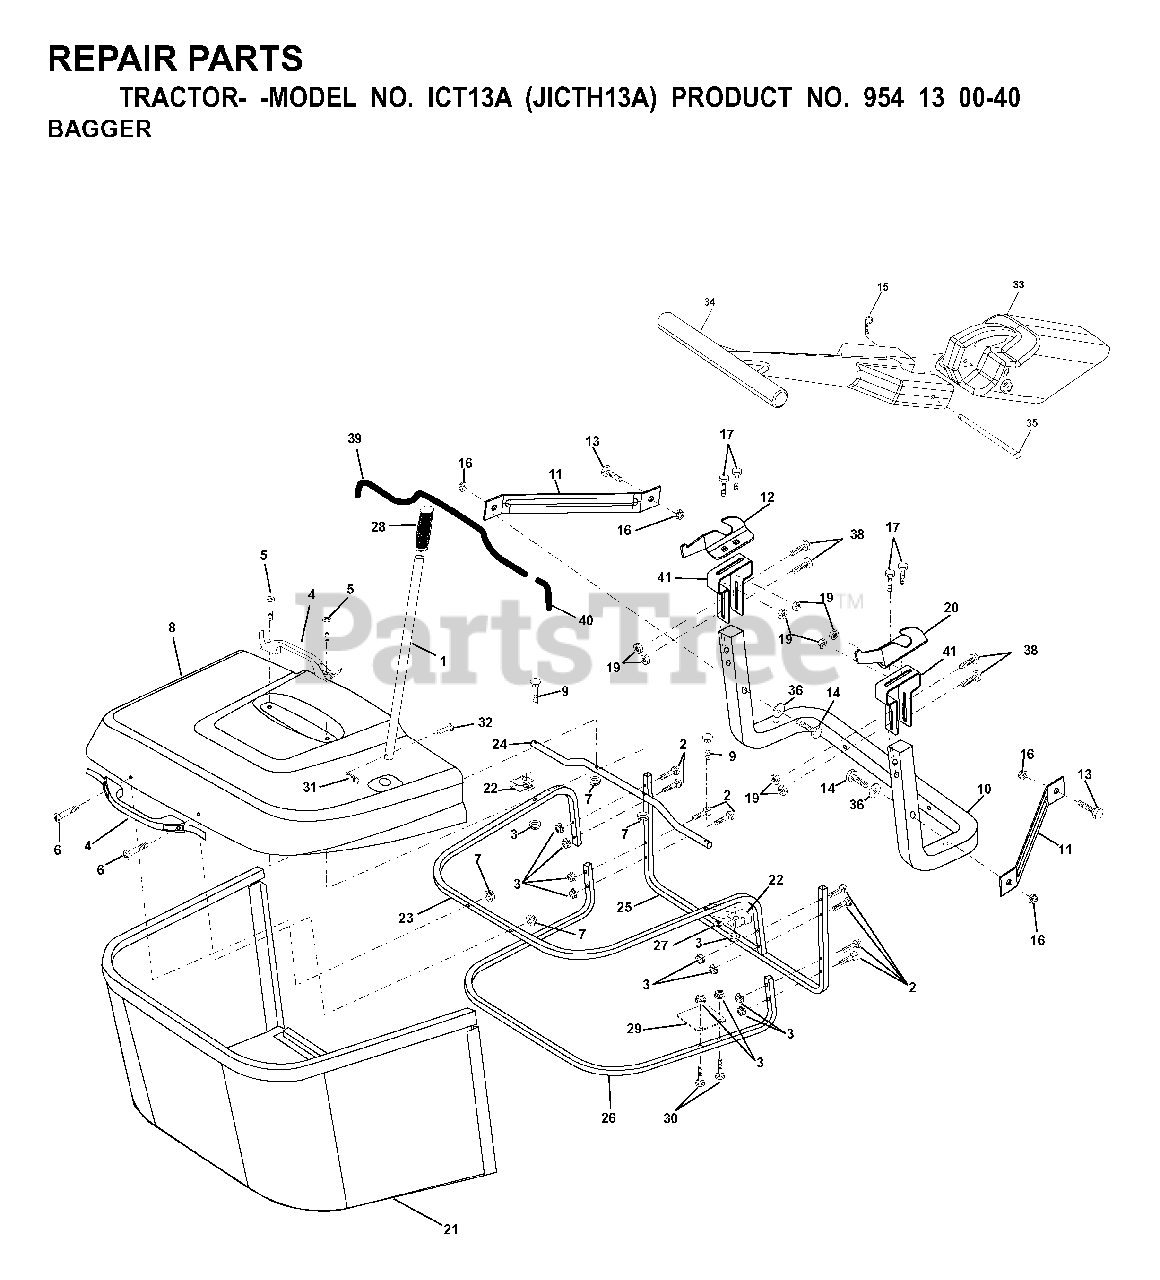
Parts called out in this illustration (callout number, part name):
1	TUBE HANDLE
3	NUT T
5	SCREW.PAN.HEAD
10	TUBE
11	BRACKET
15	RETAINER-SPRNG RB
16	NUT LOCK FLG 3/8-16 UNC
17	BOLT
19	NUT.71038.31-18.HEX.NYLOCK
20	BRACKET
21	BAG
22	BRACKET
23	TUBE
24	TUBE
26	TUBE
28	GRIP.HANDLE.BLACK
31	RETAINER M
32	RIVET,DRILLED
33	PLUG
35	PIN
36	WASHER
38	BOLT.5/16-18X2.5
39	TRIM
40	TRIM
41	BRKT, BAGGER
